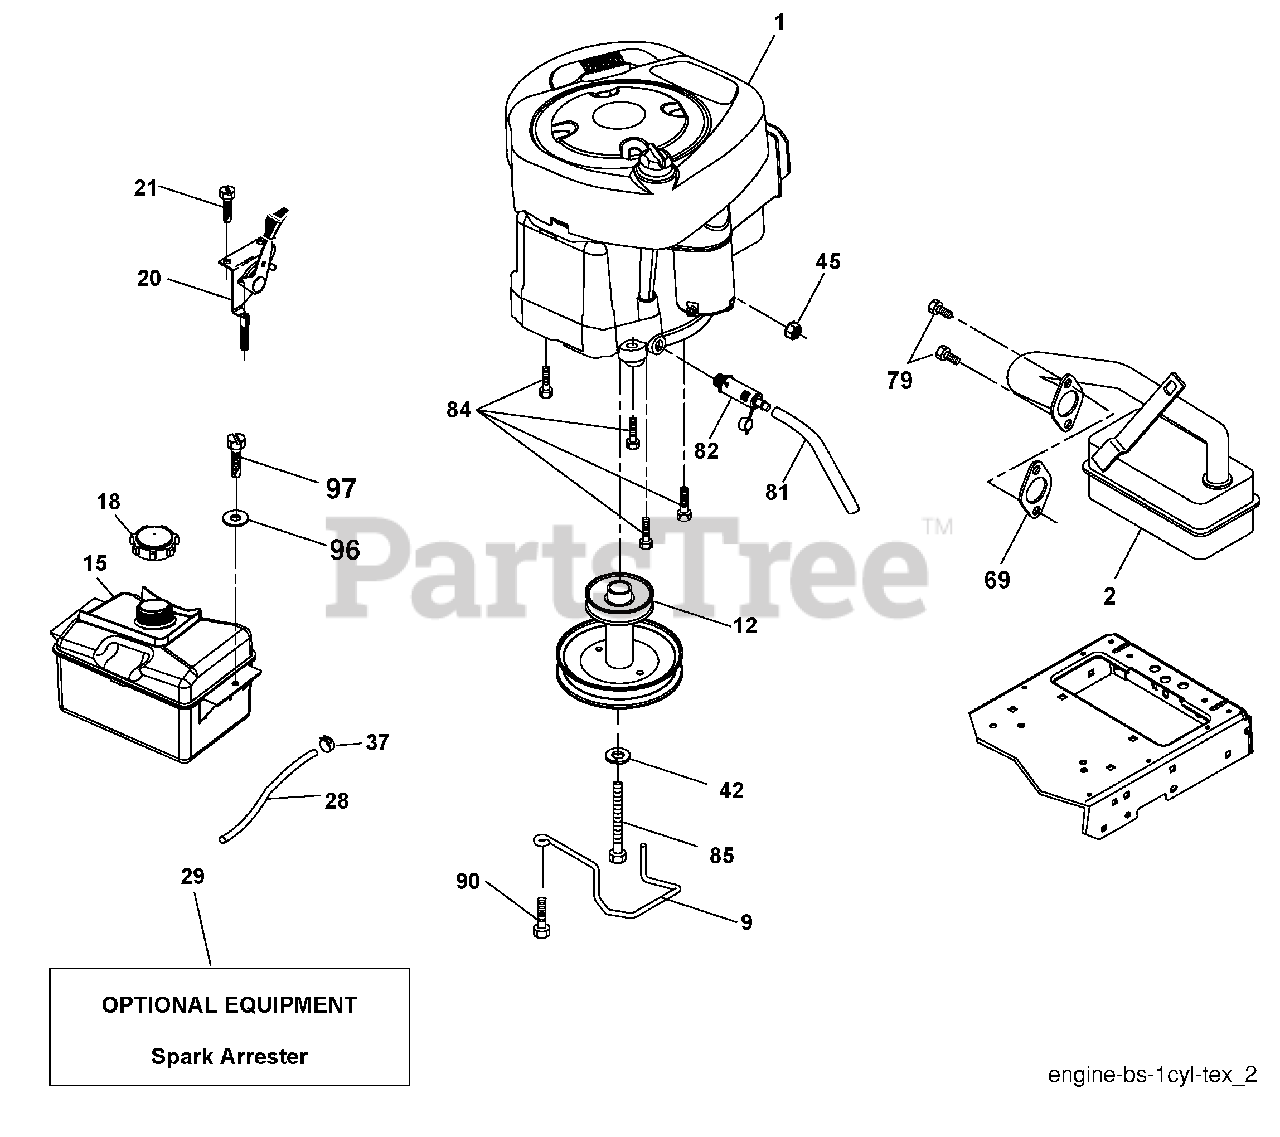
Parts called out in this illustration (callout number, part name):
2	Muffler
9	Keeper Belt Engine
12	Pulley Engine
15	Tank Fuel
18	Cap Asm
20	Control Throttle
21	Screw 10 x 3/4 Single Lead-Hex
28	Fuel Line
29	Spark Arrester Kit
37	Clamp Hose
42	Washer Lock 7/16
45	Nut Keps Hex 1/4-20 unc
69	Gasket
79	Screw Socket HD 5/16-18 x .75
81	Tube Drain Oil Easy
82	Plug Drain Oil
84	Screw 3/8-16 x 1-1/4
85	Bolt 7/16-20 x 4 x GR 5-1.5
90	Screw 3/8-16 x 1
96	Washer 9/32 x 7/8 x 16 Ga.
97	Screw 1/4-20 x 3/4
